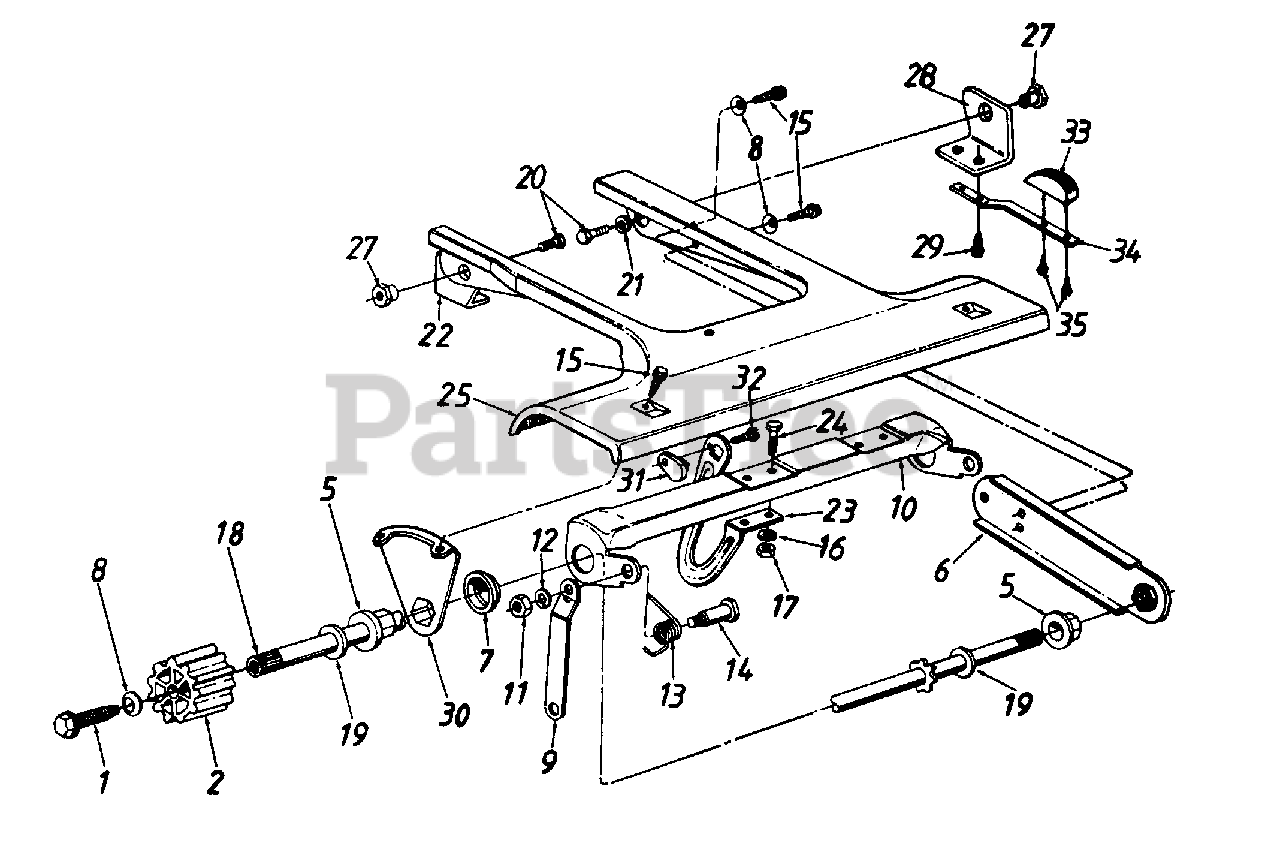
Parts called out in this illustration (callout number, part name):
1	Hex Scr. 1/4-20 x .75" Lg. (Gr. 5)
2	Wheel Drive Pinion
5	Hex Flange Brg. .504" I.D.
8	Bell-Wash. .265" I.D. x .75" O.D.
11	Hex Nut 5/16-18 Thd.
12	L-Wash. 5/16" I.D.
13	Torsion Spring - R.H.
14	Shoulder Bolt .437" Dia.
15	Hex Wash. Hd. AB-Tap Scr. 1/4 x .62" Lg.
16	L-Wash. 1/4" I.D.
17	Hex Nut 1/4-20 Thd.
18	Drive Shaft Ass'y.
19	Fl-Wash. .531" I.D. x .93" O.D.
20	Hex Bolt 3/8-16 x .5" Lg.
21	L-Wash. 3/8" I.D.
32	Hex B-Tap Scr. #10 x .44" Lg.
33	Chain Tensioner
34	Cantilever Spring
35	Hex B-Tap Scr. #10 x .38" Lg.
